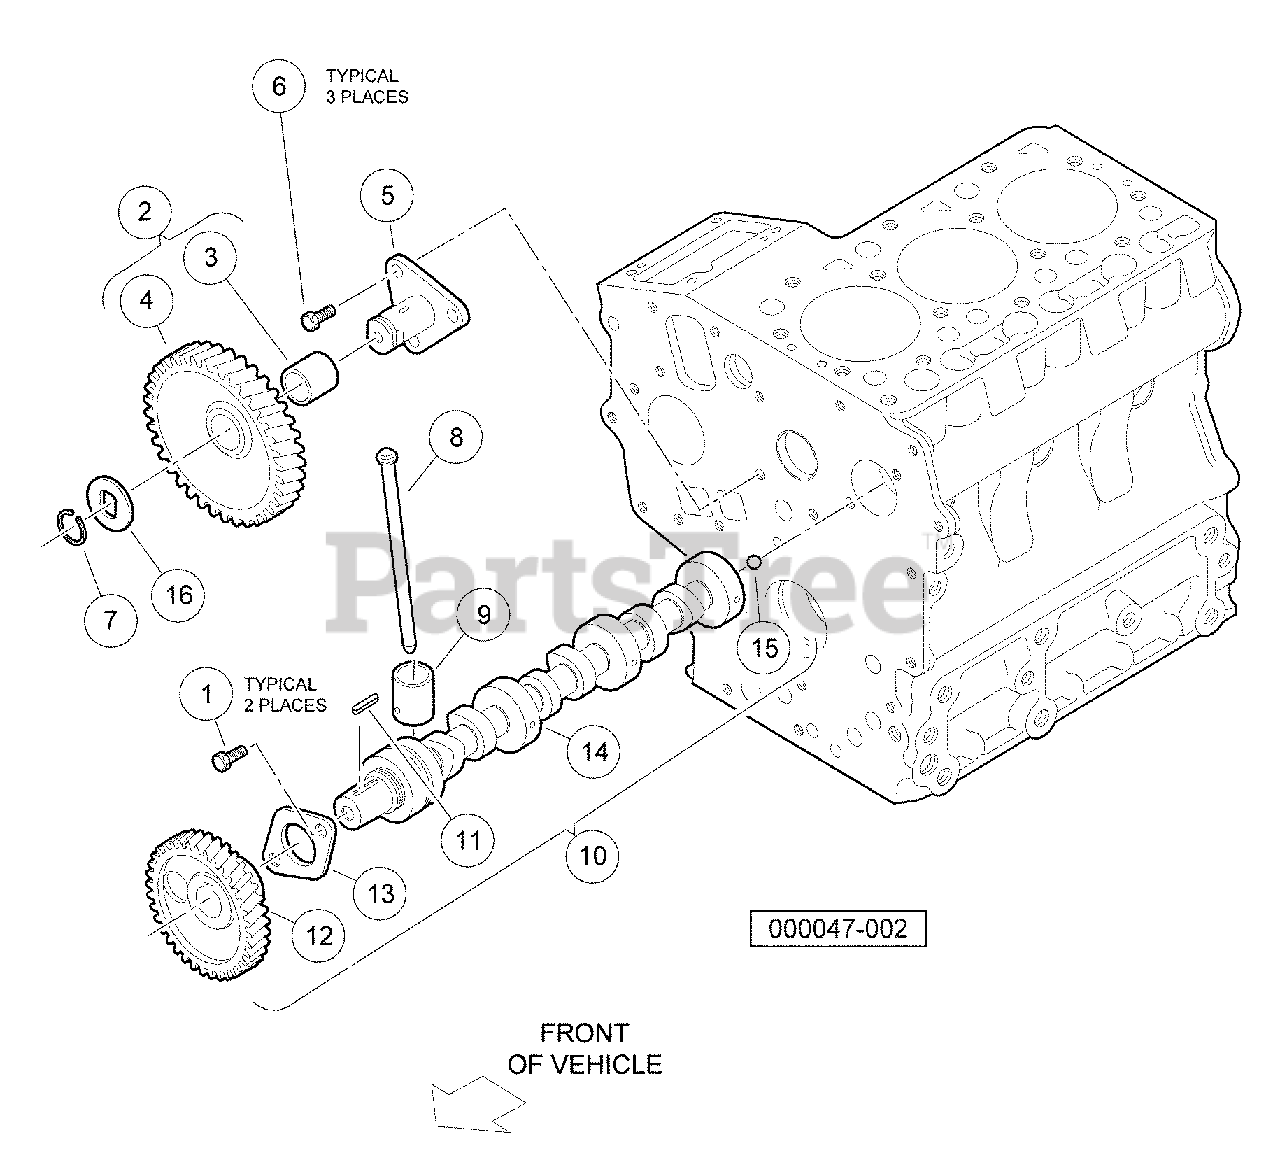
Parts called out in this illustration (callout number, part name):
1	Bolt, D722, Cam End
2	Gear, Idle
3	Bushing, D722 Idle Gear
4	Gear, Idle
5	Shaft, Idle Gear
6	Bolt, M6 X 1 X 14
7	Ring, Snap
10	Assy Camshaft, Long
11	Key, Feather, Long Camshaft
13	Stopper, Camshaft
14	Camshaft
15	Ball, Check
16	Collar, Idle Gear
